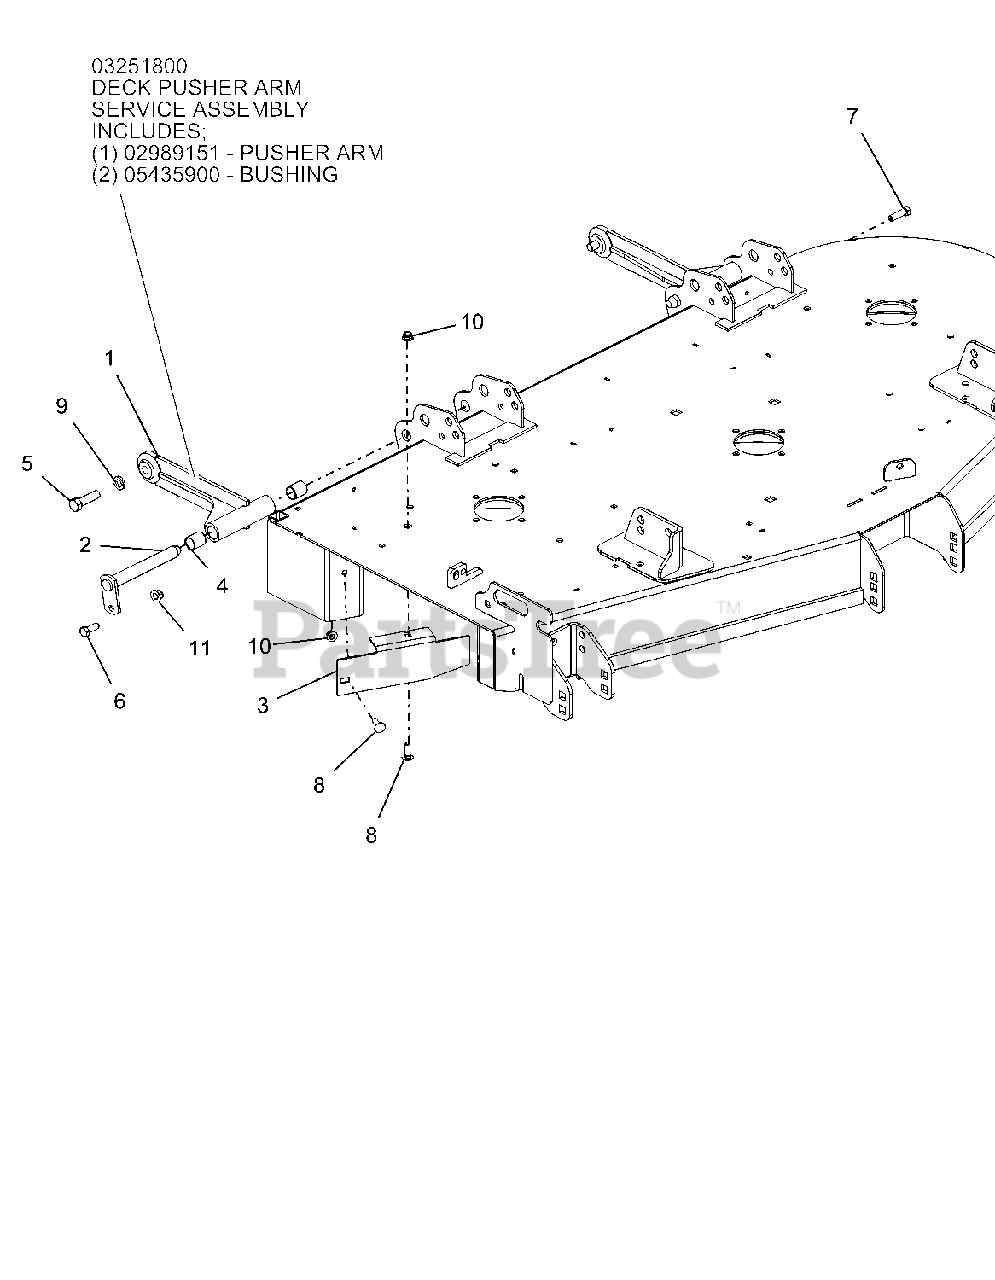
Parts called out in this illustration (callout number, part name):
1	DECK PUSHER ARM WLDMT - BLK
1	DECK PUSHER ARM SERVICE ASSEMBLY
1	PUSHER ARM
1	BUSHING
2	WLDMT, MOWER MTG. PIN
3	BAFFLE, DISCHARGE, 52"-RED
4	BRG, .750 X .875 X 1.000
5	BLT-HEX .50-13X1.75 G5 YZ EP80
6	BLT-HEX .38-16X1.00 GR5 YWZC
7	BLT-HEX .38-16X1.25 GR5 YWZC
8	BLT-RDHDSQSHNK .31-18X1.00 G5 Y
9	WSHR-LK .50X.125 REG YWZC
10	NUT-LK-NYL-FLG .31-18 YWZC
11	NUT-LK-NYL-FLG .38-16 YWZC
